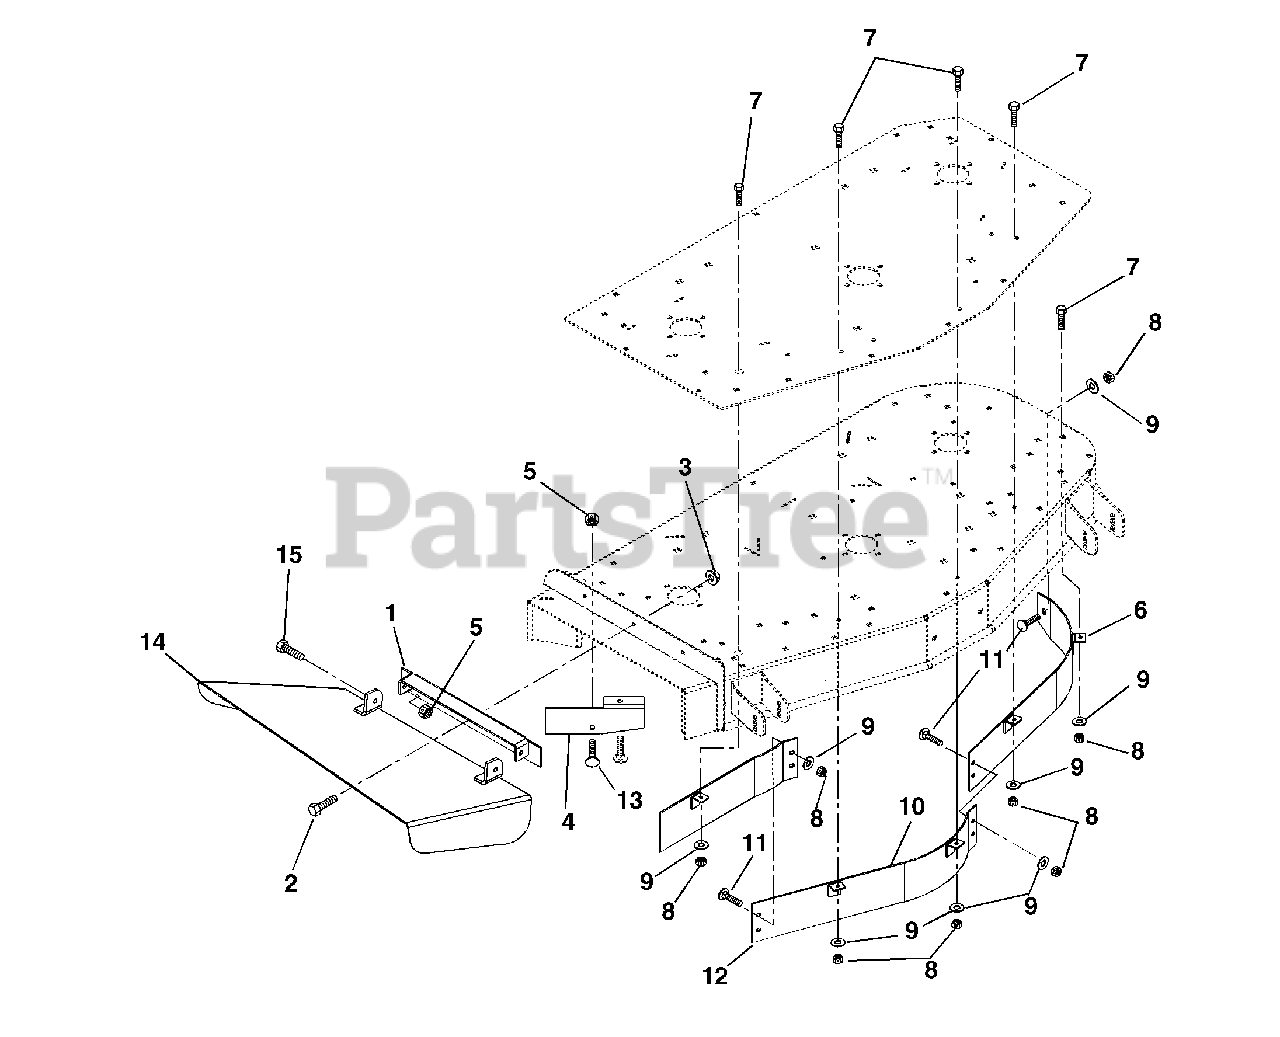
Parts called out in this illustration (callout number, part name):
1	Weldment, Discharge Chute Bracket
2	Bolt-Hex .38-16 x 1.00 Grade 5
3	Nut-Locking-Flange .38-16
4	Deflector 50"
5	Nut-Locking-Center .38-16
6	Weldment, 50" Left Hand Baffle-Upper
7	Bolt-Hex .31-18 x 1.00 Grade 5
8	Nut-Locking-Nylon .31-18
9	Washer-Flat-Steel .312 x .734 x .065
10	Weldment, 50" Center Baffle-Up
11	Bolt-Round Head Square Neck .31-18 x .75 Grade 5
12	Weldment, 50" Right Hand Baffle-Upper
13	Bolt-Round Head Square Neck .38-16 x 1.00 Grade 2
14	Weldment, Discharge Chute 50"
15	Bolt-Hex .38-16 x 1.00 Grade 5
16	50" Discharge Cover
17	50" Mulch Kit
